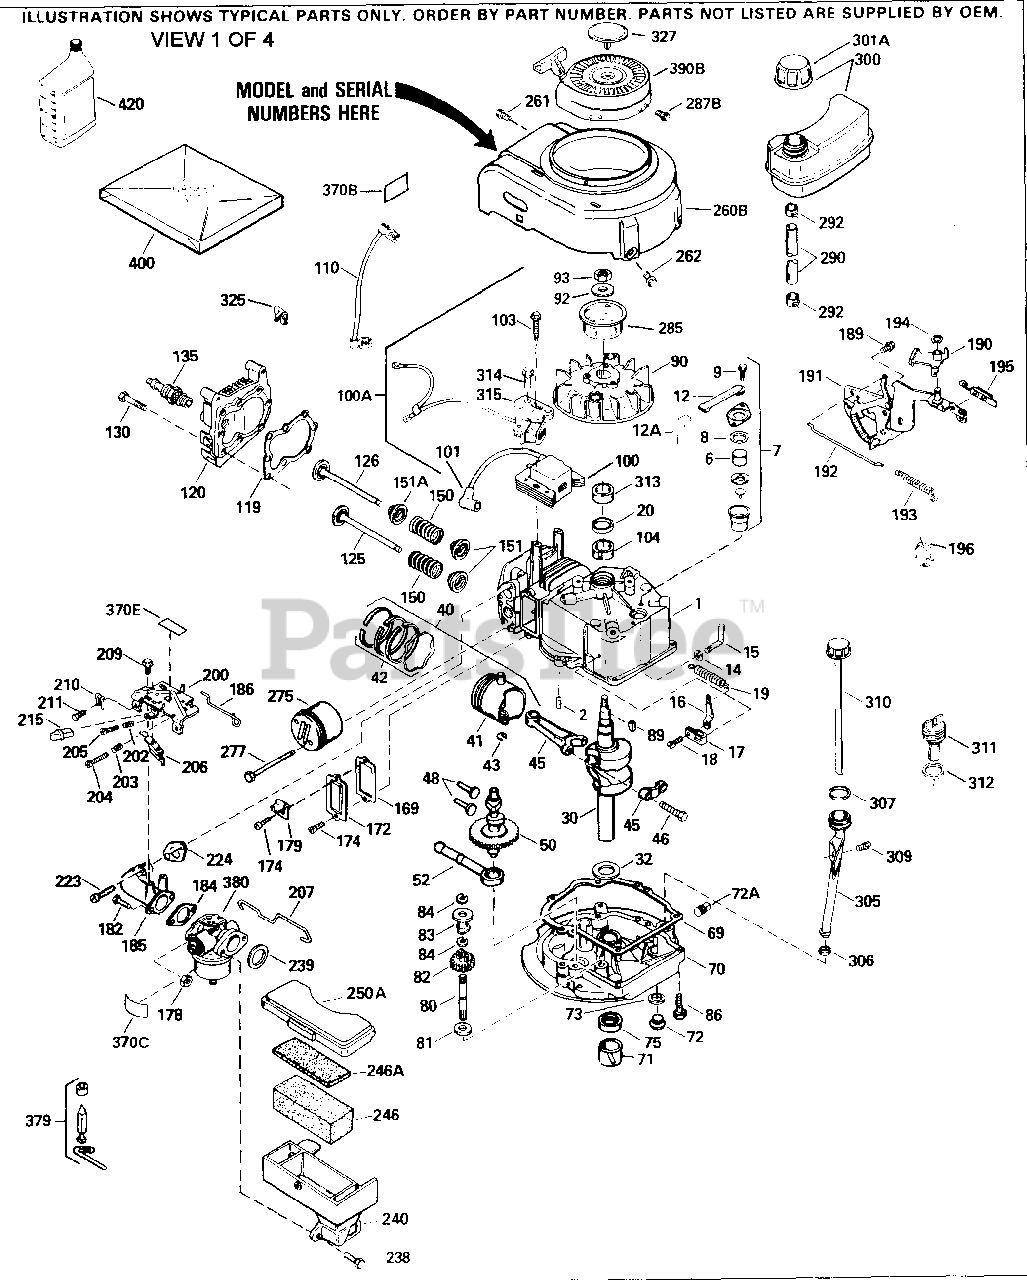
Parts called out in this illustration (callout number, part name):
1	"Cylinder Ass'y. (Incl. 2, 8, 9 & 20) (2-1/2")
2	Dowel Pin
6	Element, Breather
7	Breather Ass'y. Incl. 6, 8, 9, 12 & 1 2A
8	* Gasket, Breather
9	Screw, 10-24 x 9/16"
12	Tube, Breather
14	Flat Washer
15	Rod, Governor (Incl. 14)
16	Lever, Governor
17	Clamp, Governor lever
18	Screw, 8-32 x 5/16"
19	Spring, Extension
20	Seal, Oil
30	Crankshaft Ass'y.
40	Piston, Pin & Ring Set (Std.) 2-1/2" Bore
40	Piston, Pin & Ring Set (.010" OS)
40	Piston, Pin & Ring Set (.020" OS)
41	Piston & Pin Ass'y. (Incl. 43)(Std.) 2-1/2"
41	Piston & Pin Ass'y. (Incl. 43) .010" OS
41	Piston & Pin Ass'y. (Incl. 43) .020" OS
42	Ring Set (Std.)
42	Ring Set (.010" OS)
42	Ring Set (.020" OS)
43	Piston Pin Retaining Ring
45	Rod Assy., Connecting (Incl. 46)
46	Bolt, Connecting rod
48	Valve Lifter
50	Camshaft
52	Oil Pump Ass'y.
69	* Gasket, Mounting flange
70	Mounting Flange Incl. 72, 72A, 73, 7 5 & 80
72	Plug, Oil drain (Incl. 73)
73	* Drain Plug Gasket Not req. W/plastic plug
75	Oil Seal
80	Shaft, Governor
81	Washer, Flat
82	Gear Assy., Governor (Incl. 81)
83	Spool, Governor
84	Retaining Ring
86	Screw, 1/4-20 x 1-1/4"
89	Flywheel Key
90	Flywheel
92	Washer, Belleville
93	Nut, Flywheel
100	Solid State Ignition NOTE: Specs with this ignition system can still servi ce individual components (points, con denser, etc.)See Div. 3, Sec. A, page TVS75 & TVS90 4,Reference numbers 12 2 thru 134. (This coil has been super seded to 730207 solid st
100	Magneto-to-Solid State Conversion Kit (Includes solid state module, solid state flywheel key, and instructions. )(Use as required on external ignitio n engines only.)
103	Screw, Torx T-15, 10-24 x 1"
110	Ground Wire (Incl. 120)
119	* Gasket, Cylinder head
120	Head, Cylinder
125	Exhaust Valve (Std.) (Incl. 151)
125	Exhaust Valve (1/32" OS) (Incl. 151)
126	Intake Valve (Std.) (Incl. 151)
126	Exhaust Valve (1/32" OS) (Incl. 151)
130	Screw, 5/16-18 x 1-1/2"
135	Resistor Spark Plug (RJ17LM)
150	Spring, Valve
151	Cap, Lower valve spring
169	* Gasket, Valve spring box
172	Cover, Valve spring box
174	Screw, 10-24 x 1/2"
178	Nut & Lock Washer 1/4-28
182	Screw, 1/4-28 x 7/8"
184	* Gasket, Carburetor
185	Pipe, Intake (Incl. 224)
186	Link, Governor spring
206	Terminal (Use as required)
207	Link, Throttle
223	Screw, 1/4-20 x 1"
224	* Gasket, Intake pipe
238	Screw, 10-32 x 5/8"
239	* Gasket, Air cleaner
240	Body, Air cleaner (Black)
246	Air Filter (Poly) (also available in Packaged Part #740023B)
250A	Air Cleaner Cover
261	Screw, 10-24 x 9/16"
262	Screw, 1/4-20 x 15/32"
275	Muffler Kit (Incl. 274 & 277)
277	Screw, 1/4-20 x 2-1/4"
285	Hub, Starter
290	Fuel Line (8.62") as req.)
290	Fuel Line (Braided 16")(40cm) Use as req.
290	Fuel Line (Braided 32")(81cm) Use as req.
290	Fuel Line (Epichlorohydrin 6-3/4") 1 7cm
292	Fuel Line Clamp
300	Fuel Tank (Incl. 292 & 301)
305	Oil Fill Tube
306	Gasket, Oil fill tube
306	"O" Ring This "O" ring is required wi th metal fill tube only when replacem ent mounting flange with .777 dia. oi l fill hole has been used.
307	"O" Ring
309	Screw, 10-32 x 1/2"
310	Dipstick (Incl. 307)
313	Gasket, Stator
379	Inlet Needle, Seat & Clip Assy.
380	Carburetor (Incl. 184) (Refer to Divi sion 5, Section A, page A2-10 or Fich e 8, Grid F-3for breakdown)
400	* Gasket Set (Incl. items marked *)
420	SAE 30, 4-Cycle Engine Oil (Quart)
